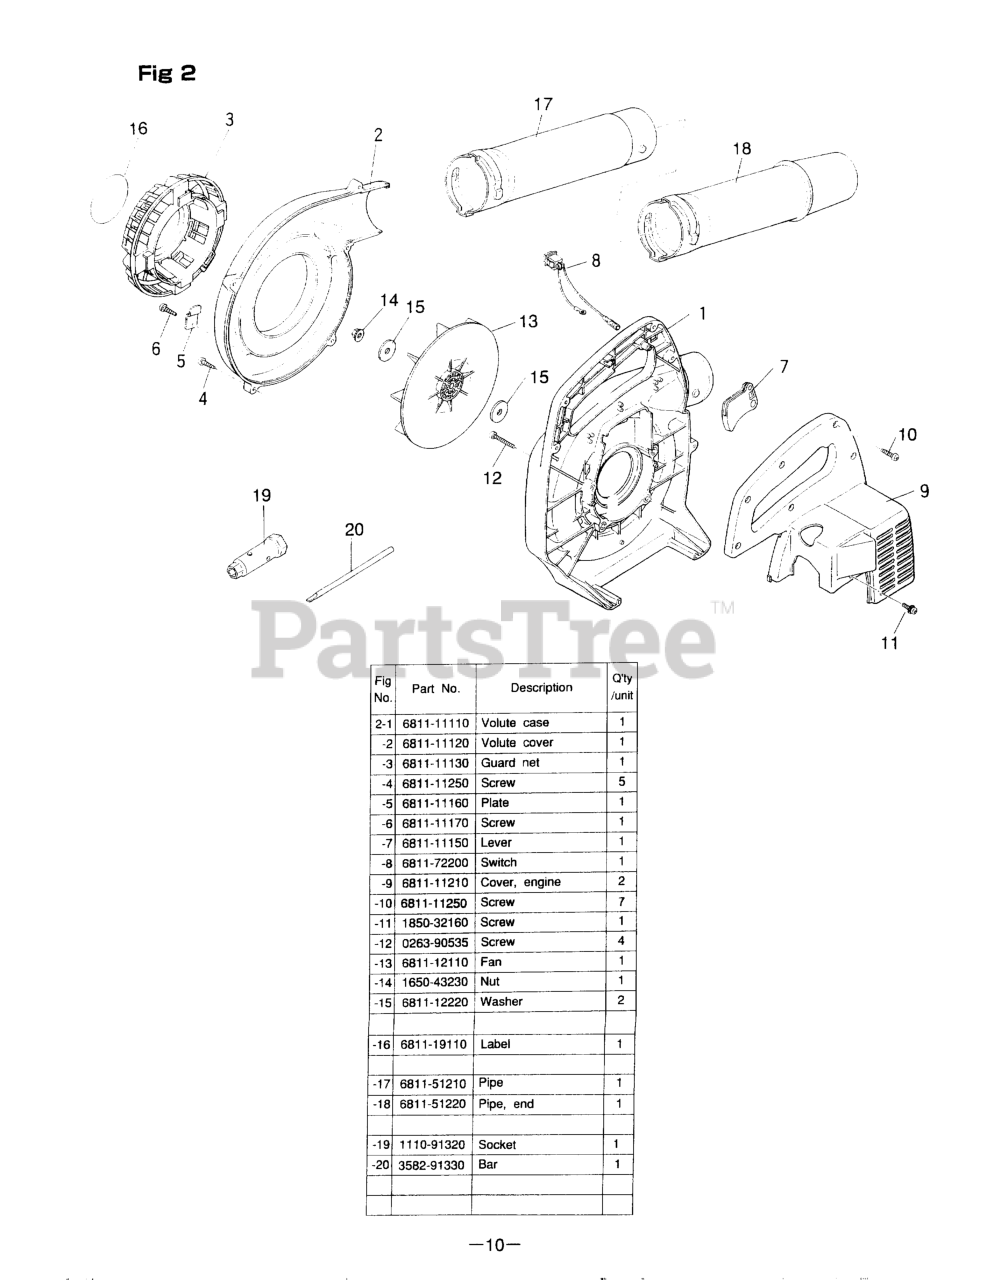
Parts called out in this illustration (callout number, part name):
1	848-L0F-55A1
2	COVER, VOLUTE
3	GUARD
4	SCREW
6	SCREW
7	LEVER
8	SWITCH
9	COVER
10	SCREW
11	SCREW, M5 x 12
12	SCREW, M5 x 35
13	FAN
15	WASHER
16	LABEL
18	PIPE, END
19	SOCKET, HEX, 3/4
